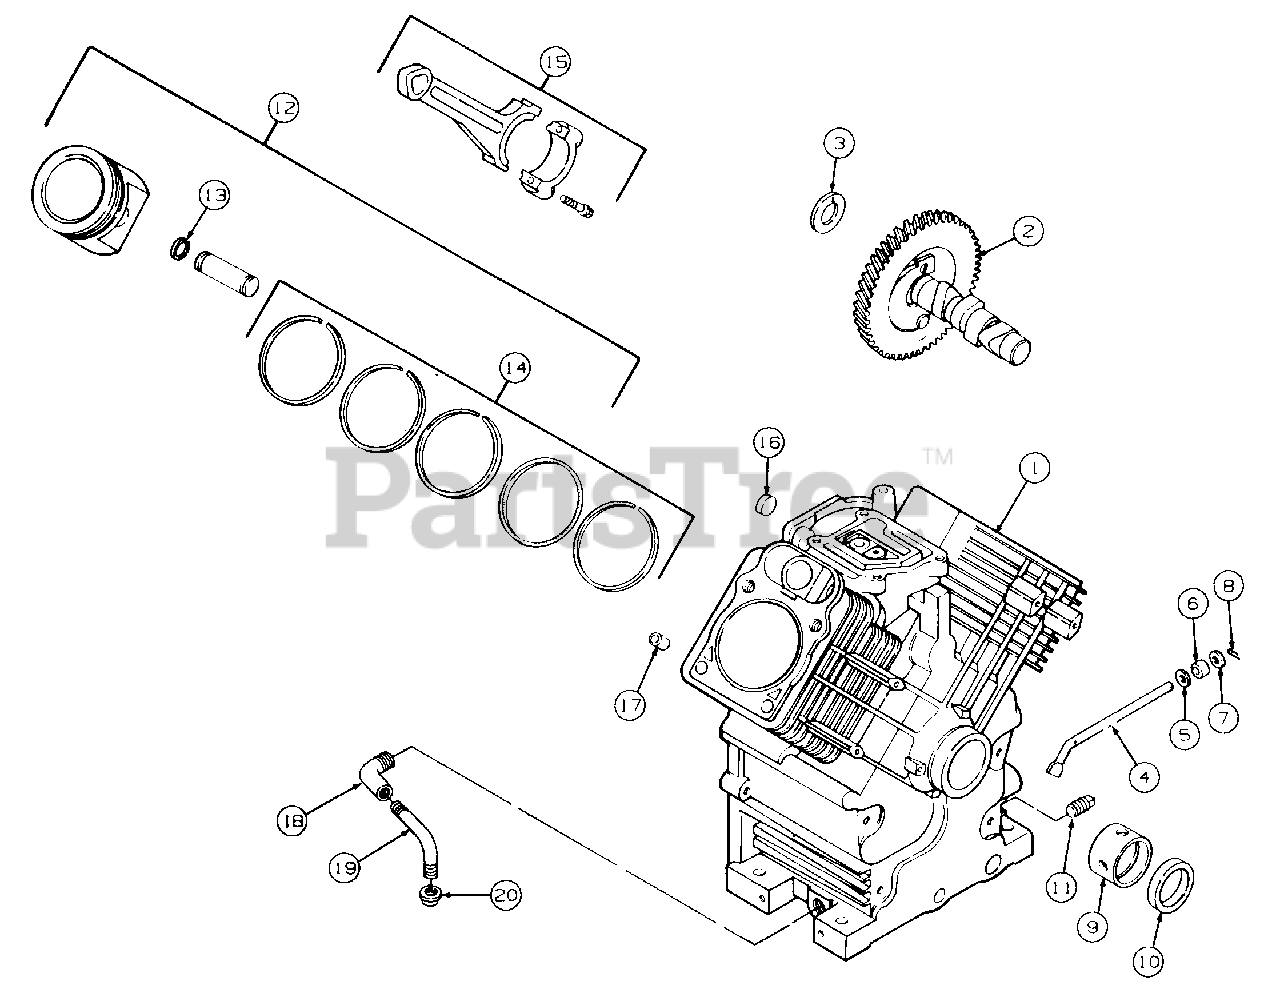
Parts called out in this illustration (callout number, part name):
1	Cylinder Block
2	Camshaft Assembly
3	Shim, Camshaft, .0320
4	Shaft, Governor Cross
6	Seal, Governor Cross Shaft
7	Washer, Plain
9	Bearing, Crankshaft
10	Seal, Oil
11	Plug, Sq Hd Solid, 3/8 NPTF
12	Piston w/Ring Set, Std
13	Retainer, Piston Pin
14	Ring Set, Std
15	Rod Connecting, Std
16	Plug, Cup
17	Pin, Dowel Locating
18	Pipe, Oil Drain, .90 Lg
19	Pipe, Oil Drain Extension
20	Cap, Oil Drain
